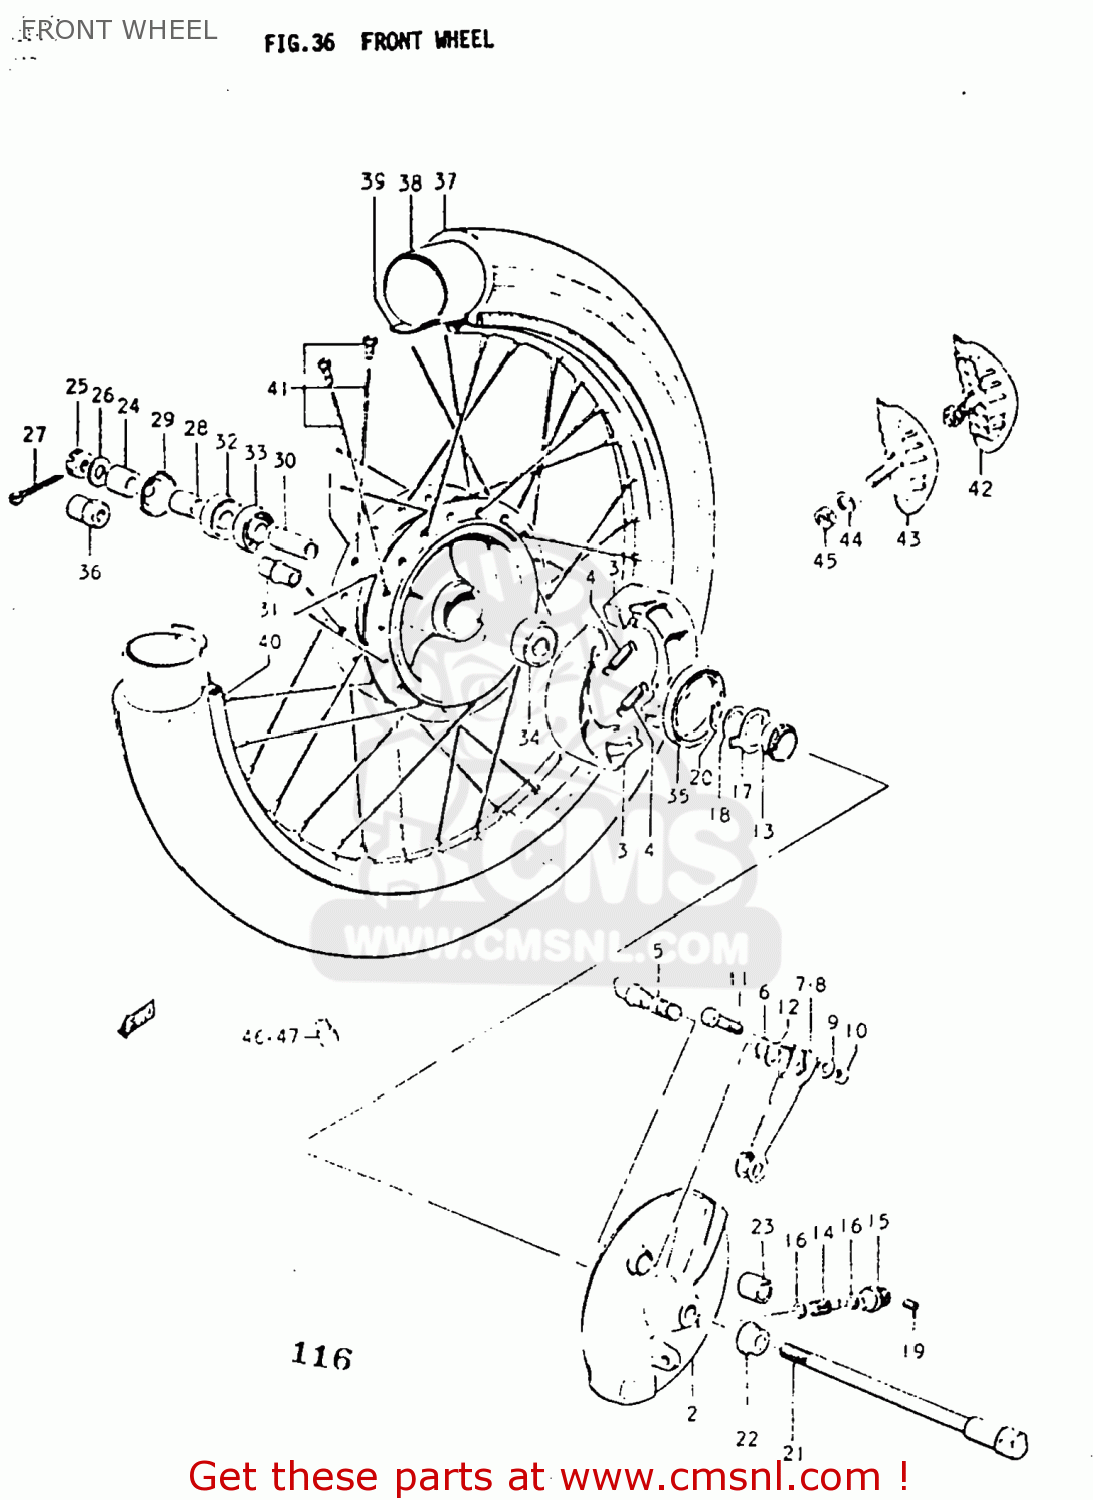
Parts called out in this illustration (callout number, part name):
1	HUB,FRONT
2	PANEL,FRONT HUB
3	SHOE,BRAKE
4	SPRING(L:34)
5	CAM,FRONT BRAKE
6	O RING(D:2.5,ID:11.4)
7	LEVER,FR BRAKE CAM
8	LEVER,FRONT BRAKE CAM
9	WASHER
10	NUT
11	BOLT
12	WASHER(12.5X20X1)
13	GEAR,SPEEDOMETER
14	PINION,SPEEDOMETER
15	BUSH,METER GEAR OUTER
16	WASHER (5.1X9X0.4)
17	DRIVER,SPEEDOMETER GEAR
18	WASHER(18.5X24X1)
19	SCREW
20	CIRCLIP
21	AXLE,FRONT
22	SPACER,FRONT AXLE,LEFT
23	SPACER (12X20X41)
24	SPACER (12X20X44)
25	NUT 12MM
26	WASHER
27	COTTER PIN
28	SPACER(12X18X16.4)
29	DUST SEAL,FRONT HUB DRUM
30	SPACER (12.6X19X52)
31	SPACER,FRONT HUB BEARING
32	OIL SEAL
33	BEARING
34	BEARING, LH
35	SEAL,OIL(48X62X7)
37	TIRE,FRONT
38	TUBE,INNER
39	PROTECTOR,WHEEL,INNER
40	RIM,FRONT WHEEL
41	SPOKE SET,FRONT
42	STOPPER,BEAD
43	STOPPER,BEAD
44	WASHER
45	NUT
46	BALANCER,WHEEL (30G)
47	BALANCER,WHEEL (50G)
